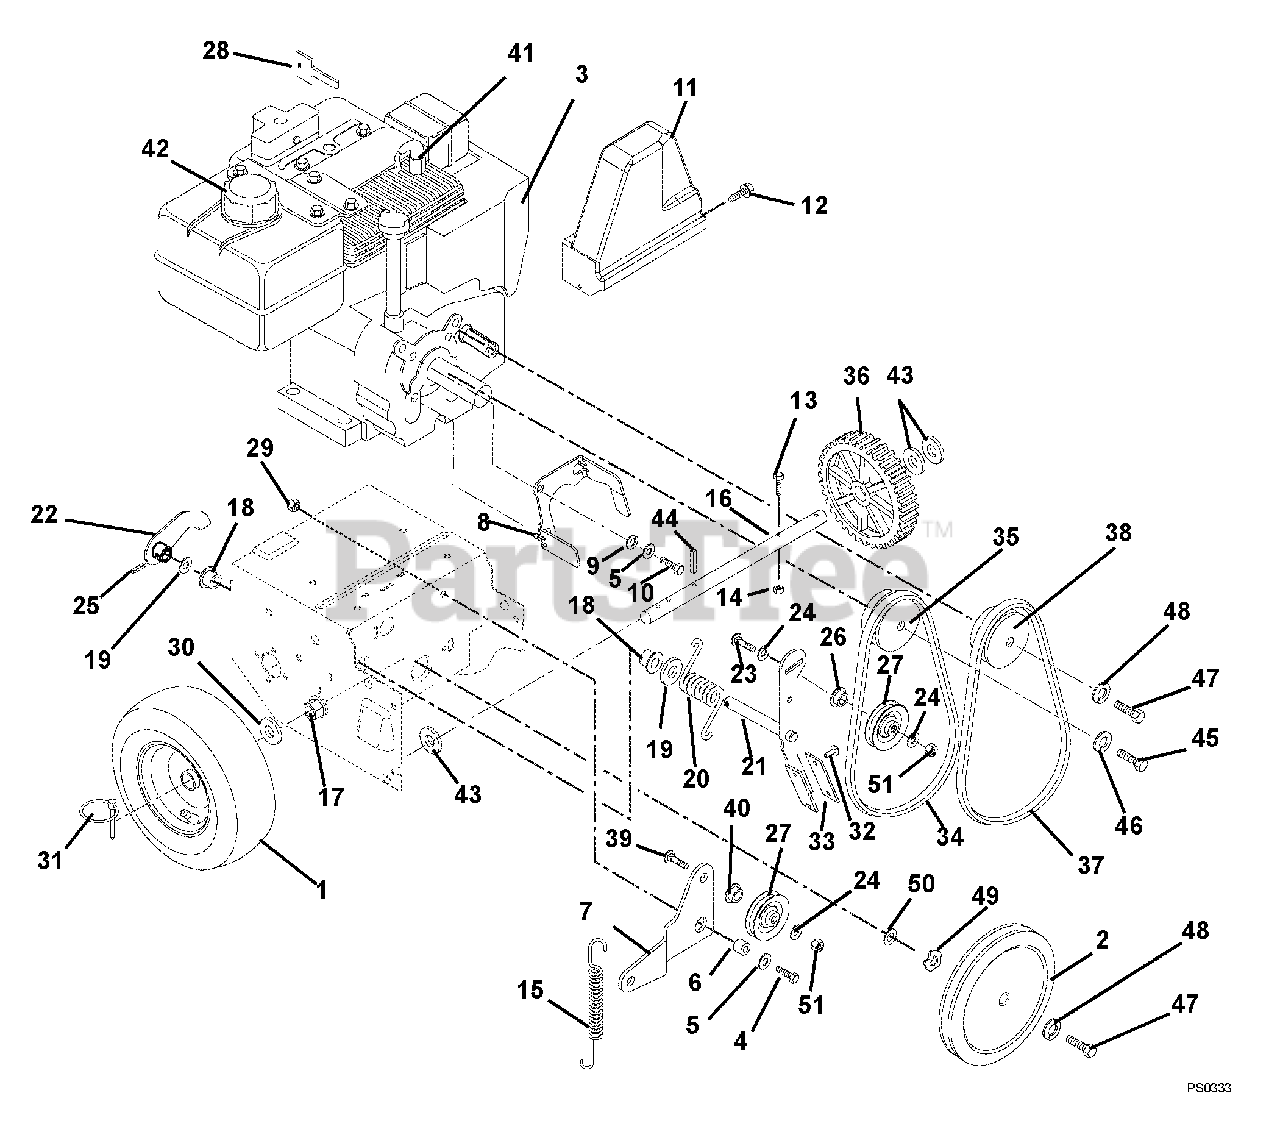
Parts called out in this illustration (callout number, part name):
1	TIRE/WHEEL, LH 13X4.00-6 PIN
1	TIRE/WHEEL, RH 13X4.00-6 PIN
1	TIRE, 2PR X-TRAC TL 13X4.00-6
1	WHEEL, 4.1-6
2	PULLEY, 3L W/HUB, .625 X 8.0
3	ENGINE,5.5HP TECOH195SA RECOIL
3	ENGINE, 7HP TEC OH195SA RECOIL
4	@BLT-HEX .31-18X.75 GR5 YWZC
5	@WSHR-FL-STL.38X.875X.083 YWZC
6	SPACER BUSHING .5 X .32 X .163
7	IDLER ARM
8	FINGER, BELT
9	WSHR-LK .312X.097 HVY YWZC
10	BLT-HEX .31-24X.75 YWZC GR5
11	BELT COVER
12	@SCR-TAP .25-20X.37 HWH YWZ TR
13	BLT-HEX .25-20X1.75 GR8 YWZC
14	@NUT-LK-CTR .25-20 YWZC
15	SG-TENS .047X.44X3.37 WLD 1.47
16	AXLE SHAFT, COMPACT W/PIN LOCK
17	BSHG-FLG .750X.873HEXX.53X1.18
18	BSHG-FLG .500X.625X.500X.750
19	WSHR-FL-STL .520X.810X.033YWZC
20	SG-TORS .148X1.0X1.53
21	CLUTCH ARM W/BRAKE PAD
22	ARM-CLUTCH
23	@BLT-RHDSHSQNK.31-18X1.25 G5YZ
24	@WSHR-FL-STL.38X.875X.083 YWZC
25	PIN-ROLL .156X.88
26	SPCR, BRG .315X.50X.688X.281
27	IDLER
28	KEY, PUSH/PULL - TECUMSEH
29	@NUT-LK-CTR .31-18 YWZC
30	WSHR-FL-STL.754X1.125X.062YWZC
31	PIN-LOK .31X1.75
32	RVT-TBLR .187X.437 RH ST PL
33	BRAKE LINING
34	BELT,4L TO BE REPLACED07200021
35	SHEAVE, ENGINE
37	V-BELT, 3L-COGGED
38	SHEAVE, CAMSHAFT OH/LH195SA
39	@BLT-RHDSSQNK .31-18X1.00 G5YZ
40	BSHG, FLG .325X.499X.26X.88
41	PLUG, SPARK
42	CAP, FUEL - TECUMSEH
43	WSHR-FL-STL .755X1.25X.125 YZ
44	PIN-ROLL .188X1.25
45	BLT-HEX .38-24X1.0 YWZC GR5
46	@WSHR-LK .38X.094 REG YWZC
47	BLT-HEX .25-28X.75 GR5 YWZC
48	WSHR-LK .250X.077 HVY YWZC
49	WSHR-WAVE .69X.84X.011
50	WSHR-THRST .625 X 1.0 X .03
51	@NUT-LK-CTR-JAM .31-18 YWZC
